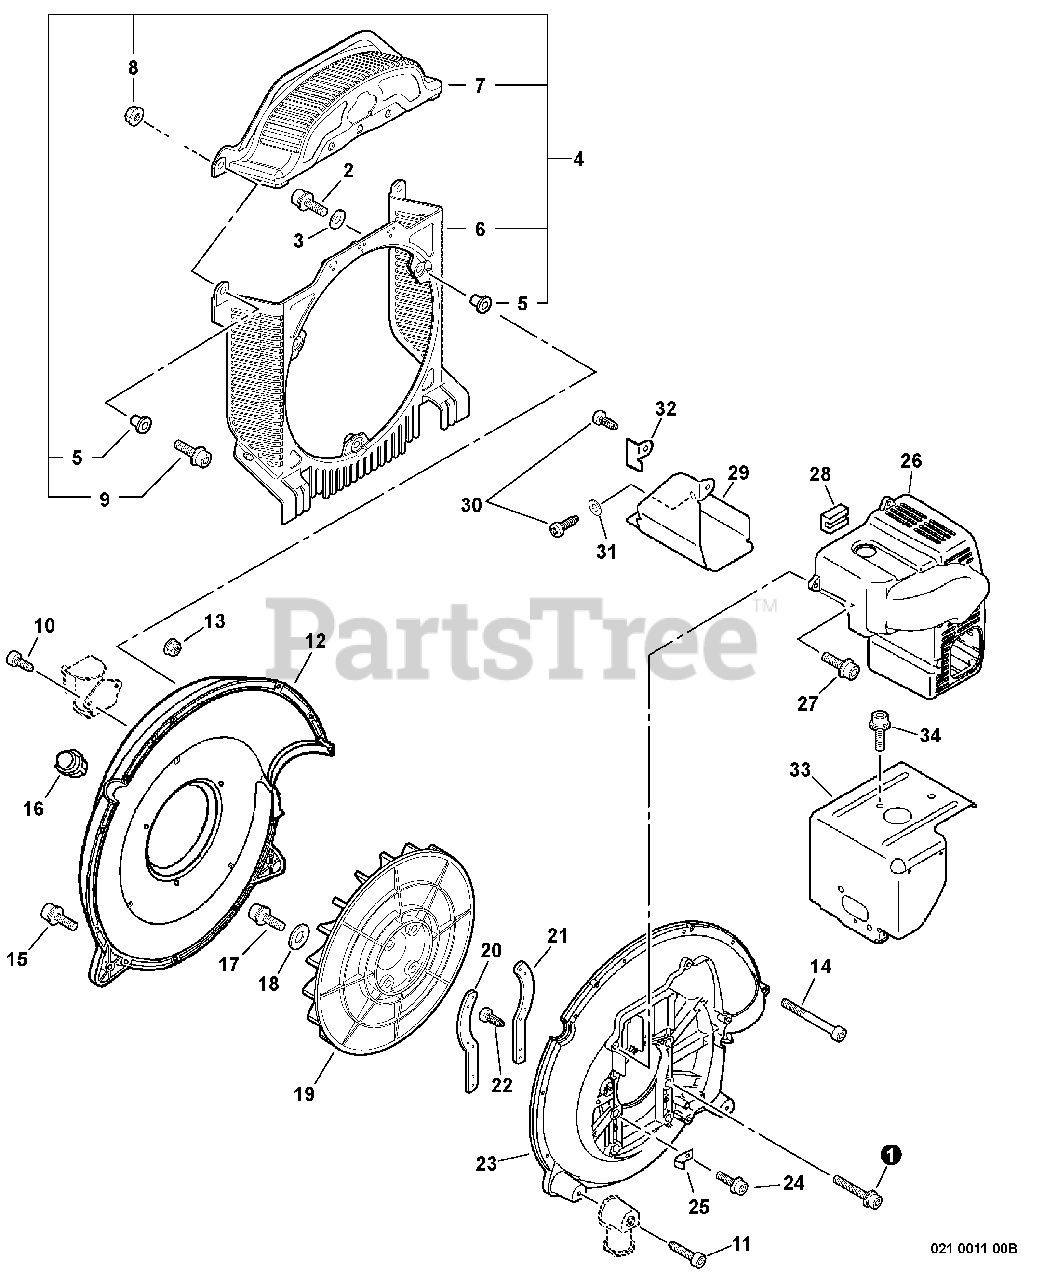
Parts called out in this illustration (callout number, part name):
1	SCREW 6×35
2	SCREW TAPPING 5×20
3	WASHER 5.5×16×2T
4	GUARD KIT, DEBRIS
6	SHIELD, DEBRIS - LOWER
7	SHIELD, DEBRIS - UPPER
8	NUT, LOCK M5
9	BOLT 5×20
10	SCREW TAPPING 5×16
11	SCREW TAPPING 5×16
12	COVER, FAN
13	NUT, FLANGE M5
14	BOLT 5×60
15	SCREW TAPPING 5×20
16	PLUG, FAN CASE
17	BOLT 6×35
19	FAN, BLOWER
20	PLATE, ENGINE (A)
21	PLATE, ENGINE (B)
22	SCREW 5×14
23	CASE, FAN
24	SCREW TAPPING 5×16
26	COVER, ENGINE
27	SCREW TAPPING 5×20
28	CUSHION
29	INSULATOR, MUFFLER
30	SCREW 5×10
31	WASHER 5.5×12×0.8
32	PLATE, ANGLE
33	COVER, CYLINDER
34	BOLT 5×8
